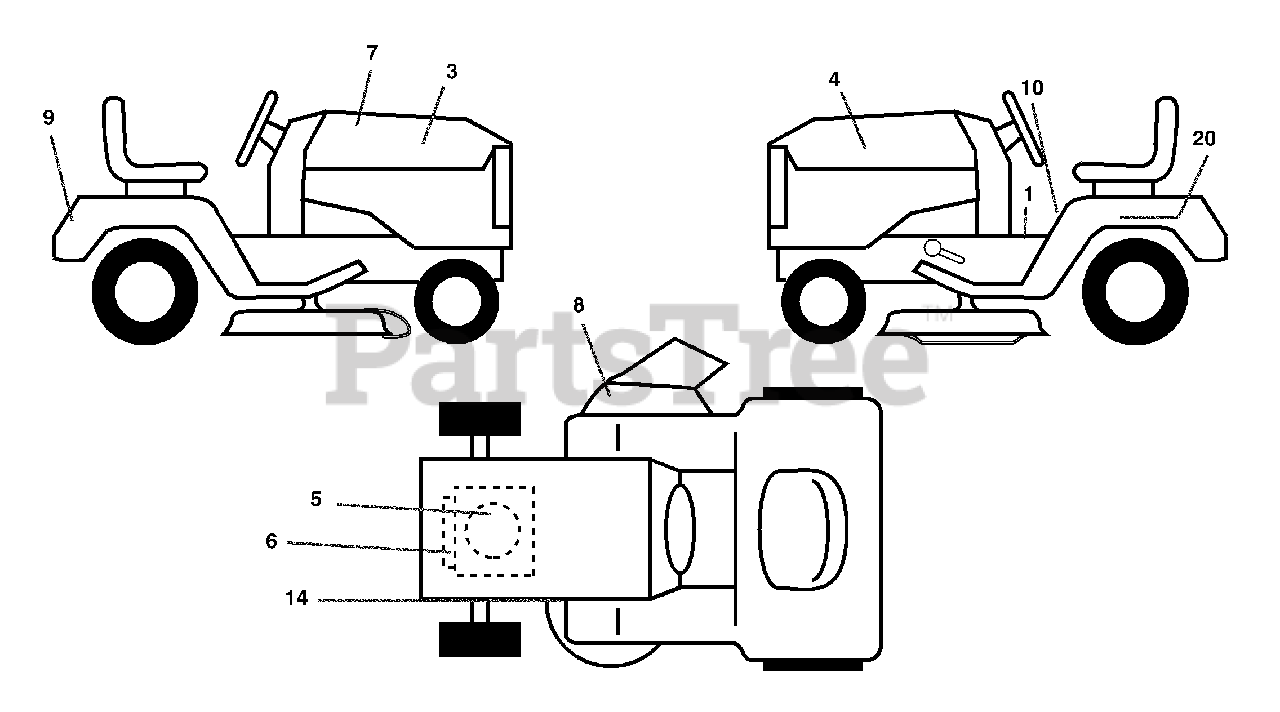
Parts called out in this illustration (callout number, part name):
1	Decal Oper. Step Thru Eng/Fr
3	Decal Hood RH
4	Decal Hood LH
5	Decal Hood Cust.
6	Decal Engine
7	Decal Replacement
8	Decal Warning
9	Decal Fender
10	Decal Fender Danger Eng/Fr
14	Decal V-Belt Schematic
20	Decal Bat Dan/Psn
